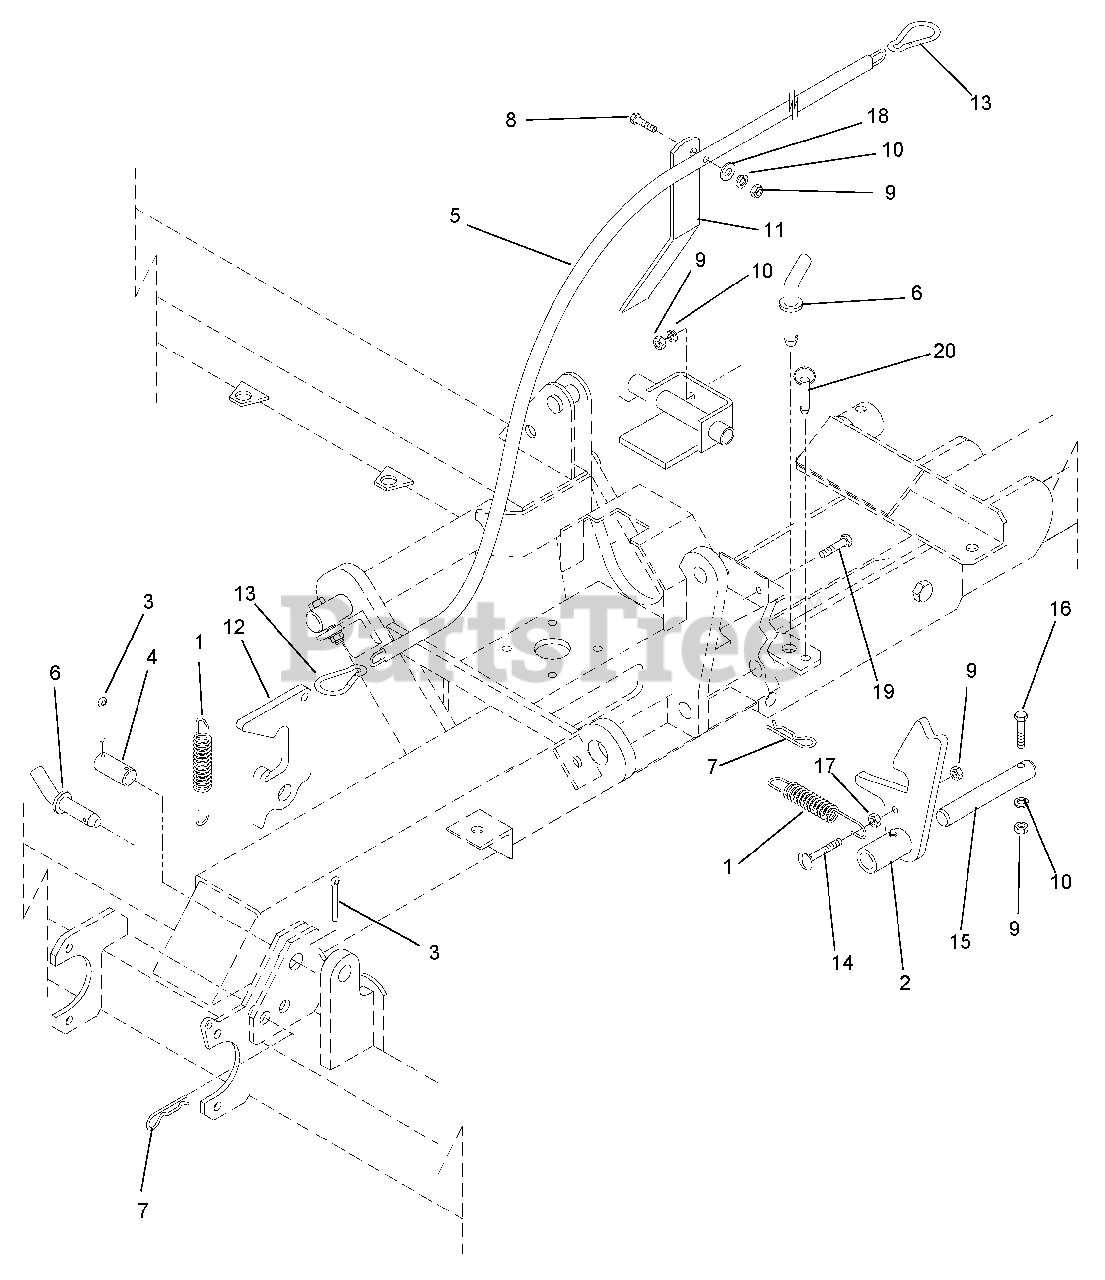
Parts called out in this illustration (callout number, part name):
1	Spring, Extension
2	Weldment, Wing Lock Right Hand
3	Pin, Cotter .156 x 1.5
5	Chain With Sleeve
7	Pin, Spring Clip
8	Cap Screw, Hex Head .38-16 x 1.5
9	Nut, Hex .38-16
10	Washer, Lock .38
11	Weldment, Handle
12	Hook, Rear Deck Locking
13	Spring, Snap
14	Bolt, Carriage .38 x 2.25
16	Cap Screw, Hex Head .38-16 x 1.75
17	Nut, Jam .38-16
18	Washer, Flat .38
19	Cap Screw, Hex Head .38-16 x 1.25
